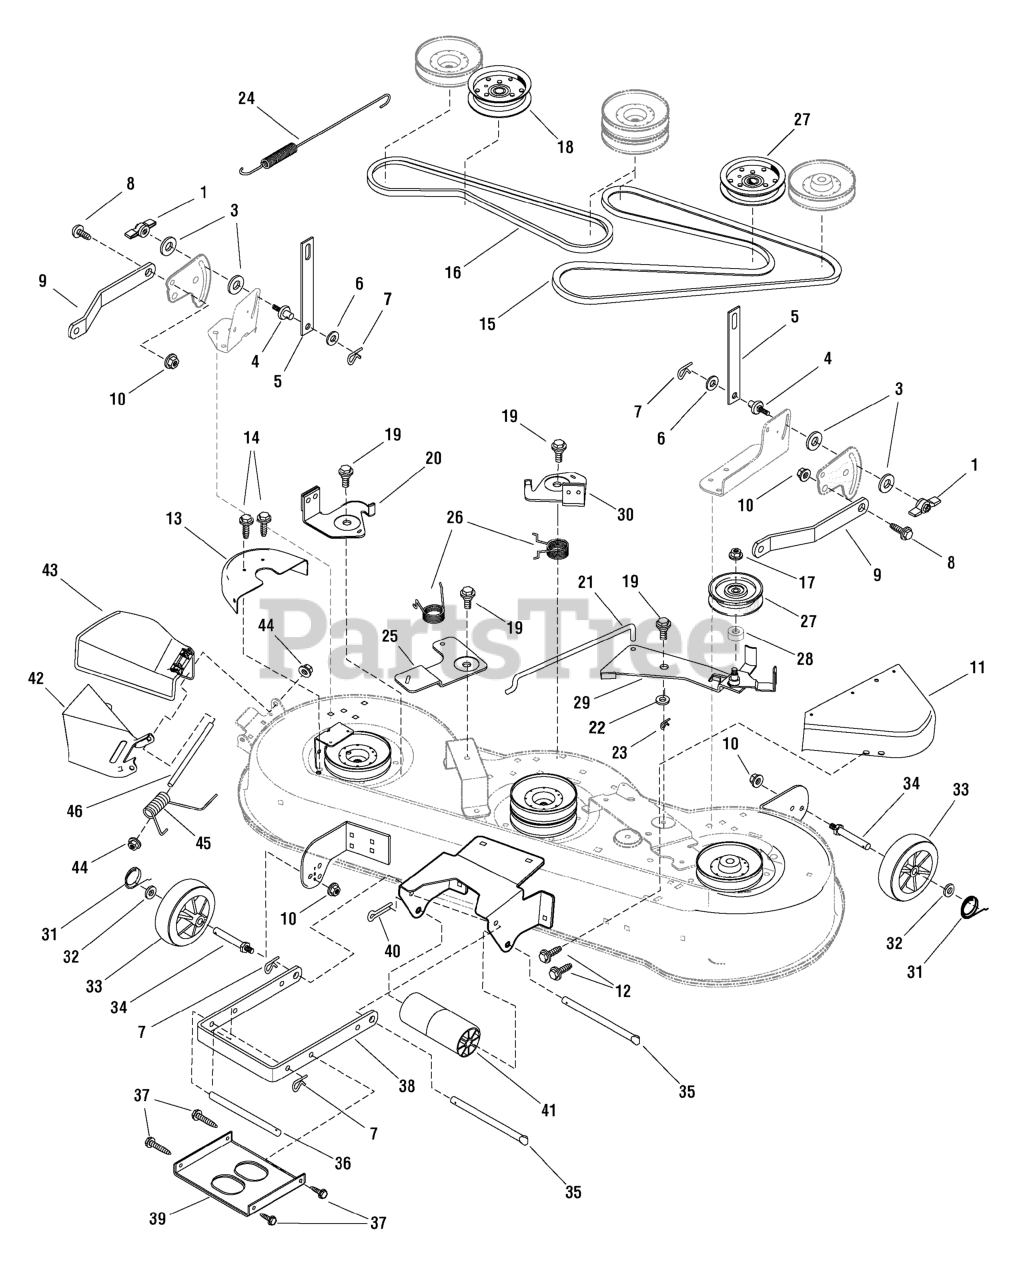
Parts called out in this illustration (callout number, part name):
1	KNOB, (5/16-18 thread)
3	FRICTION PAD
4	PIN, Hanger 3/8-16 x 1-1/4
5	LINK, Lift
6	WASHER, Flat 1
7	PIN, Hair
8	BOLT, Shoulder 3/8-16 x 1
9	BRACKET, Rear Suspension
10	NUT, Hex Flange, 3/8-16
11	COVER, Left Pulley
12	SCREW, 5/16-18 x 1/2
13	COVER, Right Pulley
14	SCREW, Thread Forming
15	BELT, Primary 46 in
16	BELT, Secondary, 46 in
17	NUT, Flange, 3/8-16
18	PULLEY, Idler, Right
19	BOLT Shoulder 3/8-16 x 3/4
20	BRAKE ASSEMBLY, Center
21	LINK, Bellcrank
22	Washer, Flat 5/8"
23	PIN, Cotter, 3/4
26	SPRING, Torsion Brake
27	PULLEY, Idler, Left
28	SPACER, 1/2" TO 17mm
29	IDLER ARM, 46 in, Left
30	BRAKE ASSEMBLY, Left
31	CLIP, Hair Pin
32	WASHER, Flat, 7/8
33	WHEEL GAGE
34	BOLT, Gauge Wheel
35	ROD, Deck Suspension
36	ROD, Hanger
37	CAPSCREW, 5/16-18
38	BRACKET, Front Suspension
40	COTTER PIN
42	DEFLECTOR, Inside
43	DEFLECTOR, Chute
44	CAP, Push On
45	SPRING, Torsion
46	ROD, Deflector
